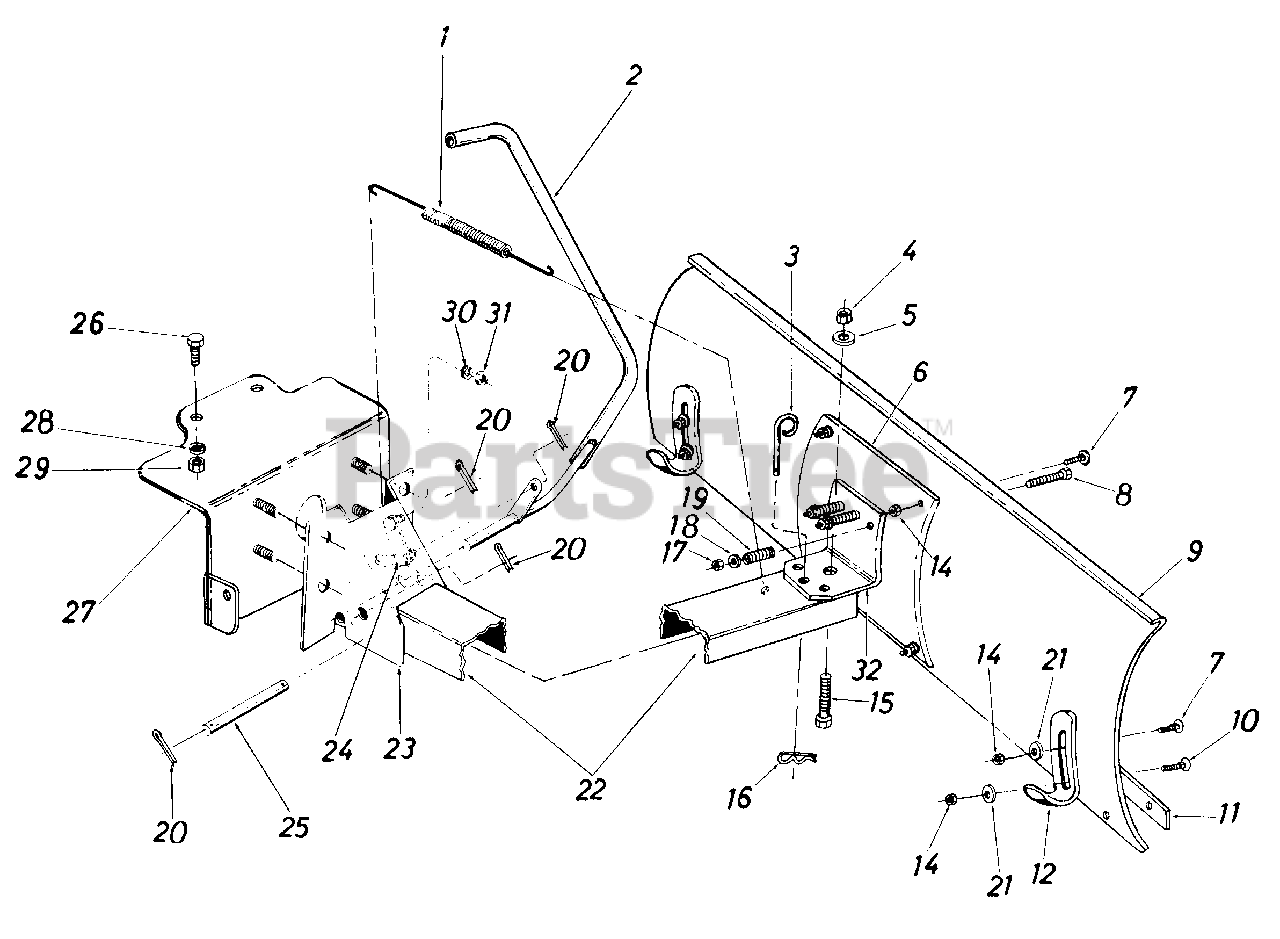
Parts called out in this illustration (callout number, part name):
1	Extension Spring
2	Lift Handle Ass'y.
3	Pivot Lock Pin
4	Hex Cent. L.-Nut 1/2-13 Thd.
5	Fl.-Wash. 17/32 I.D. x 1.25" Lg.
6	Reinforcement Plate
7	Carriage Bolt 5/16-18 x .75" Lg.
8	Hex Scr. 3/8-16 x 3.75" Lg. Grade 5
9	42" Blade
10	Carriage Bolt 5/16-18 x 1.00" Lg.
11	42" Wear Plate
12	Shoe Skid
14	HexCent. L.-Nut5/16-18Thd.
15	Hex Scr. 1/2'-13 x 1.25" Lg.
16	Hair Pin Cotter
17	Hex Cent. L.-Nut 3/8-16 Thd.
18	Fl.-Wash. 3/8" I.D.
19	Compression Spring
20	Cotter Pin 1/8" Dia. x 1.00" Lg.
21	Fl.-Wash. 5/16" I.D.
22	Push Bar Channel
23	Pivot Support Bracket
24	Lift Link
25	Channel Pivot Shaft
26	Hex Scr. 3/8-16 x 1.00" Lg. Grade 5
27	Support Bracket Ass'y.
28	L.-Wash. 3/8 I.D.
29	Hex Nut 3/8-16Thd.
30	L.-Wash. 3/8" I.D.
31	Hex Jam Nut 3/8-16 Thd.
32	Support Bracket
